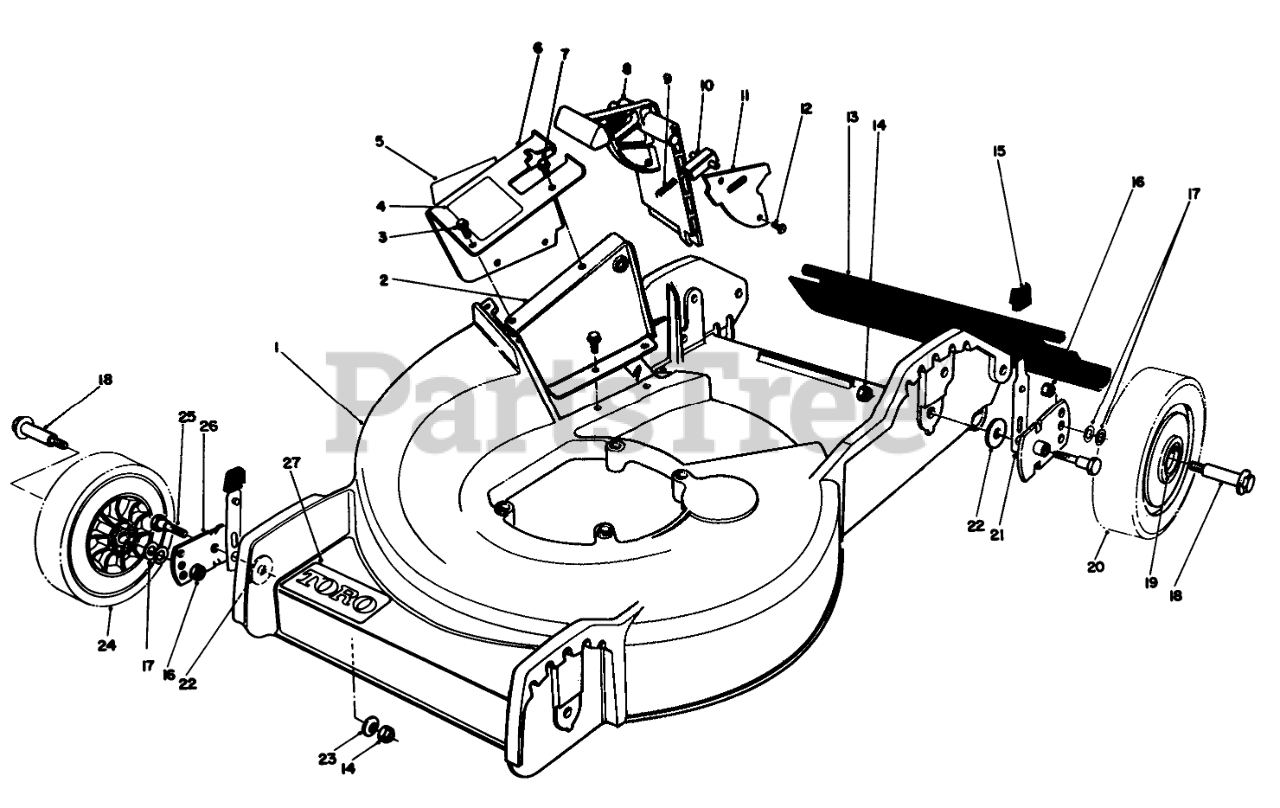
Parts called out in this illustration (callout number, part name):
1	HSG & CARTON
2	Tunnel-Inner
3	SCREW
4	DECAL - CAUTION
5	DECAL-DANGER
6	Tunnel-Outer (Incl. Ref. #4 & 5)
7	SCREW
8	Door-Mulching
9	SPRING-COMPRESSION, LATCH
10	Door Latch
11	DOOR COVER
13	SHIELD - TRAILING
14	NUT-LOCK, NI
15	KNOB-ARM
16	Nut
17	WASHER
18	BOLT-WHEEL
19	BUSHING
20	Wheel & Tire Assembly (Incl. Ref. #19)
21	SPRING ARM ASM
22	PIVOT WASHER
23	WASHER-BELLEVILLE
24	Wheel & Tire Assembly (Incl. Ref. #19)
25	5/16-18 PIVOT SCREW
26	Pivot Arm Assembly
27	DECAL
